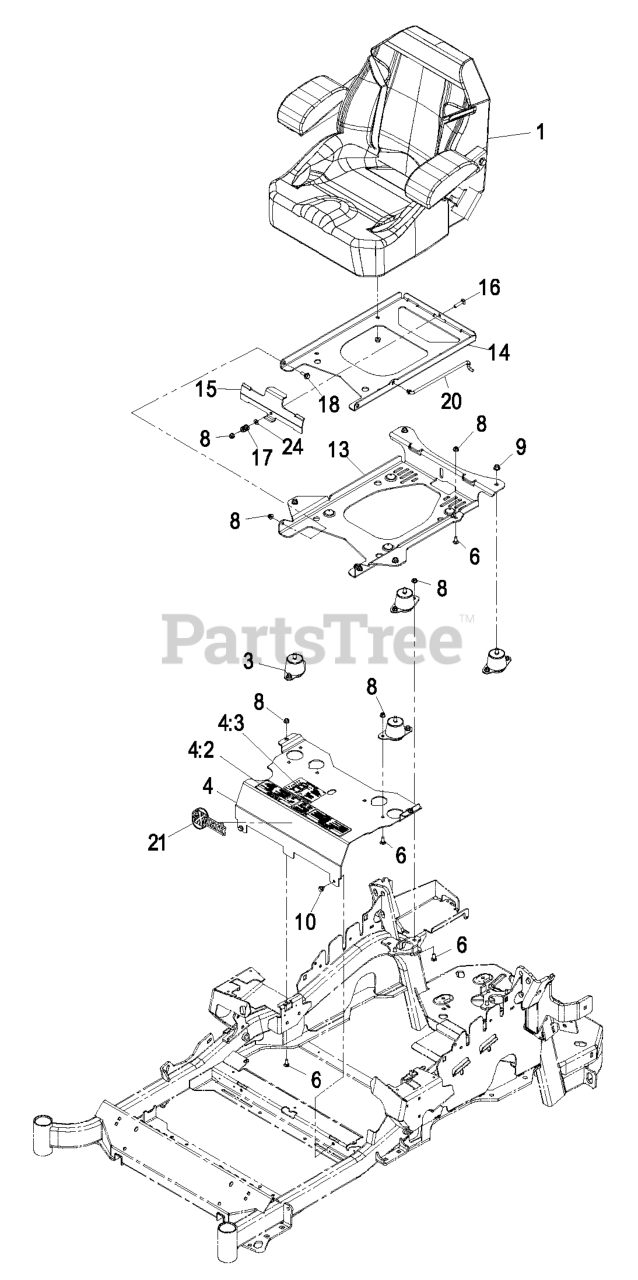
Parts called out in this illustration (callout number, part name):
3	ISOLATOR-SEAT
4	MOUNT-SEAT
4:2	DECAL-CONSOLE
4:3	DECAL-SERVICE AID
6	SCREW-CARR
8	NUT-HF, NI
9	NUT-HF, NI
13	PLATE-SUPPORT, SEAT TILT
14	PLATE-FRAME, SEAT TILT
15	PLATE-LATCH, SEAT
16	BOLT-CARR
17	SPRING-COMPRESSION
18	SCREW-SHOULDER
20	ROD-PROP
24	WASHER-PLAIN
